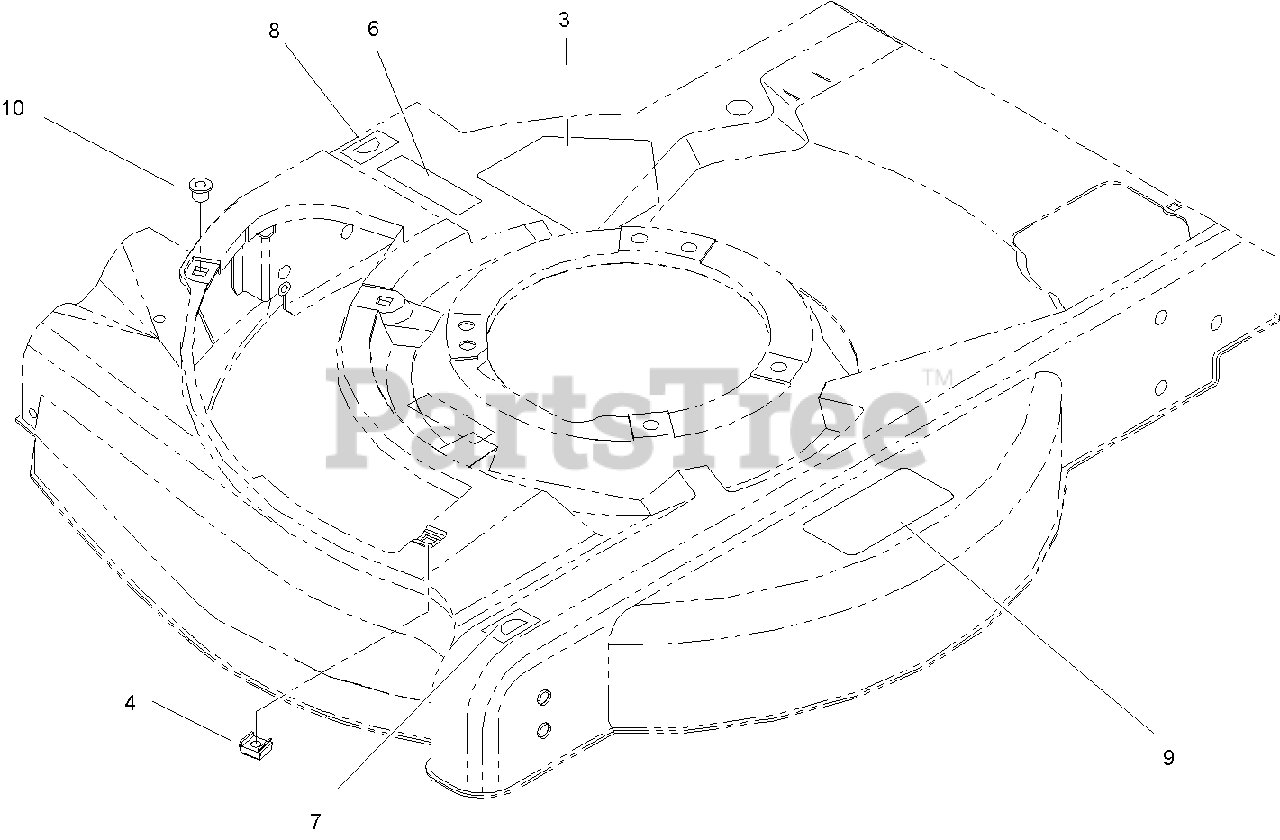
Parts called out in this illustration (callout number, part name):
3	DECAL-DANGER
4	NUT-CAGE
6	DECAL-WARNING
7	DECAL-HOC, LH
8	DECAL-HOC, RH
9	DECAL-WARNING
10	NUT-CLIP
